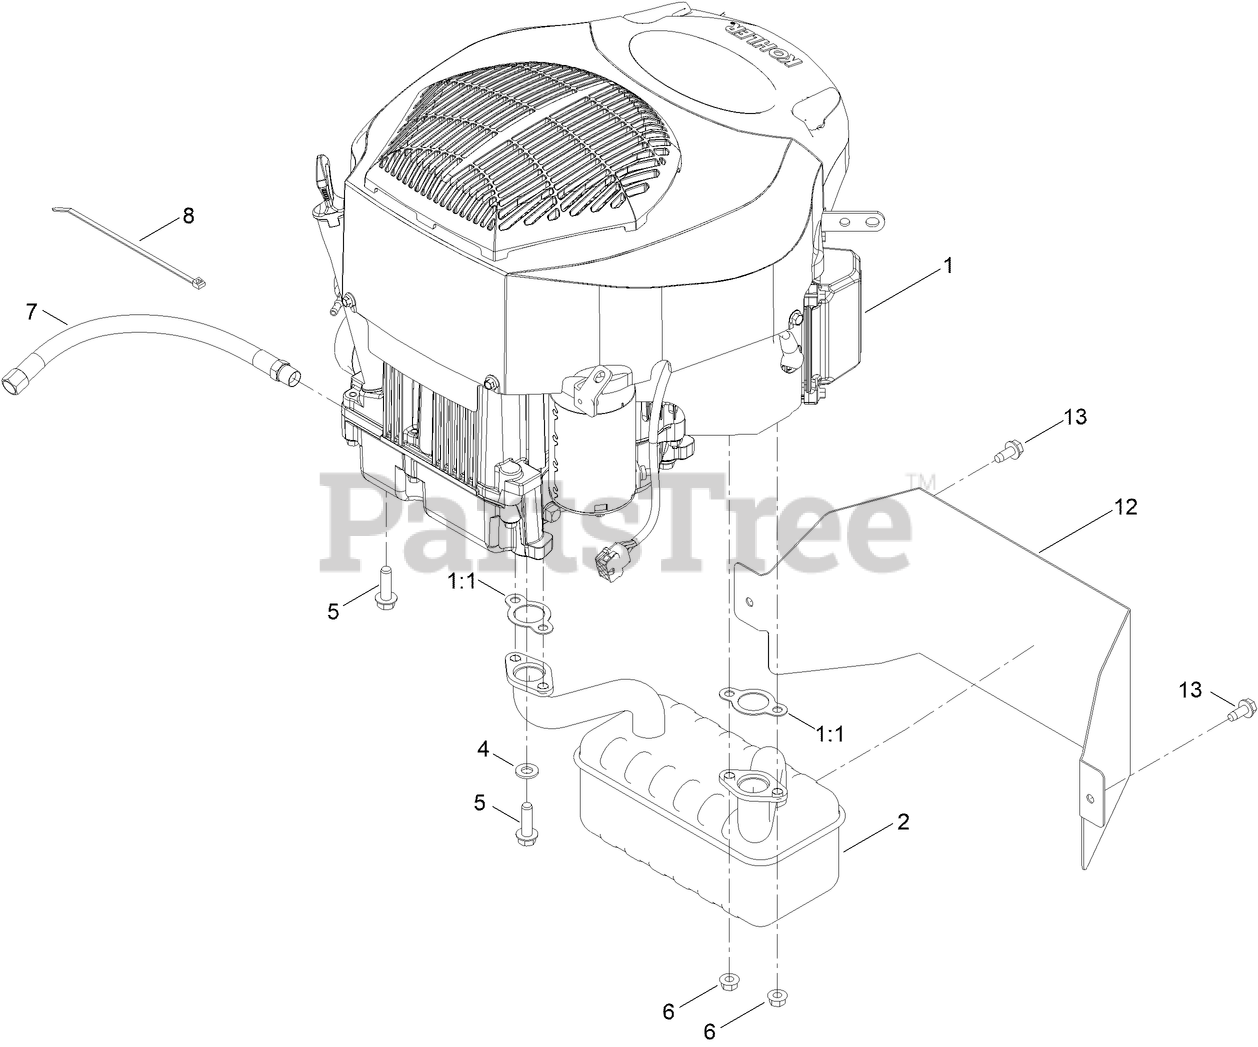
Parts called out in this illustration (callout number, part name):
1	ENGINE-KOHLER, KT735 LOW SPEED
1:1	GASKET-EXHAUST
2	MUFFLER
4	WASHER-FLAT
5	SCREW-HWH, THD ROLL
6	NUT-HF
7	HOSE-DRAIN, OIL
8	TIE-CABLE
12	HEAT SHIELD - MUFFLER
13	SCREW-HWHTF
